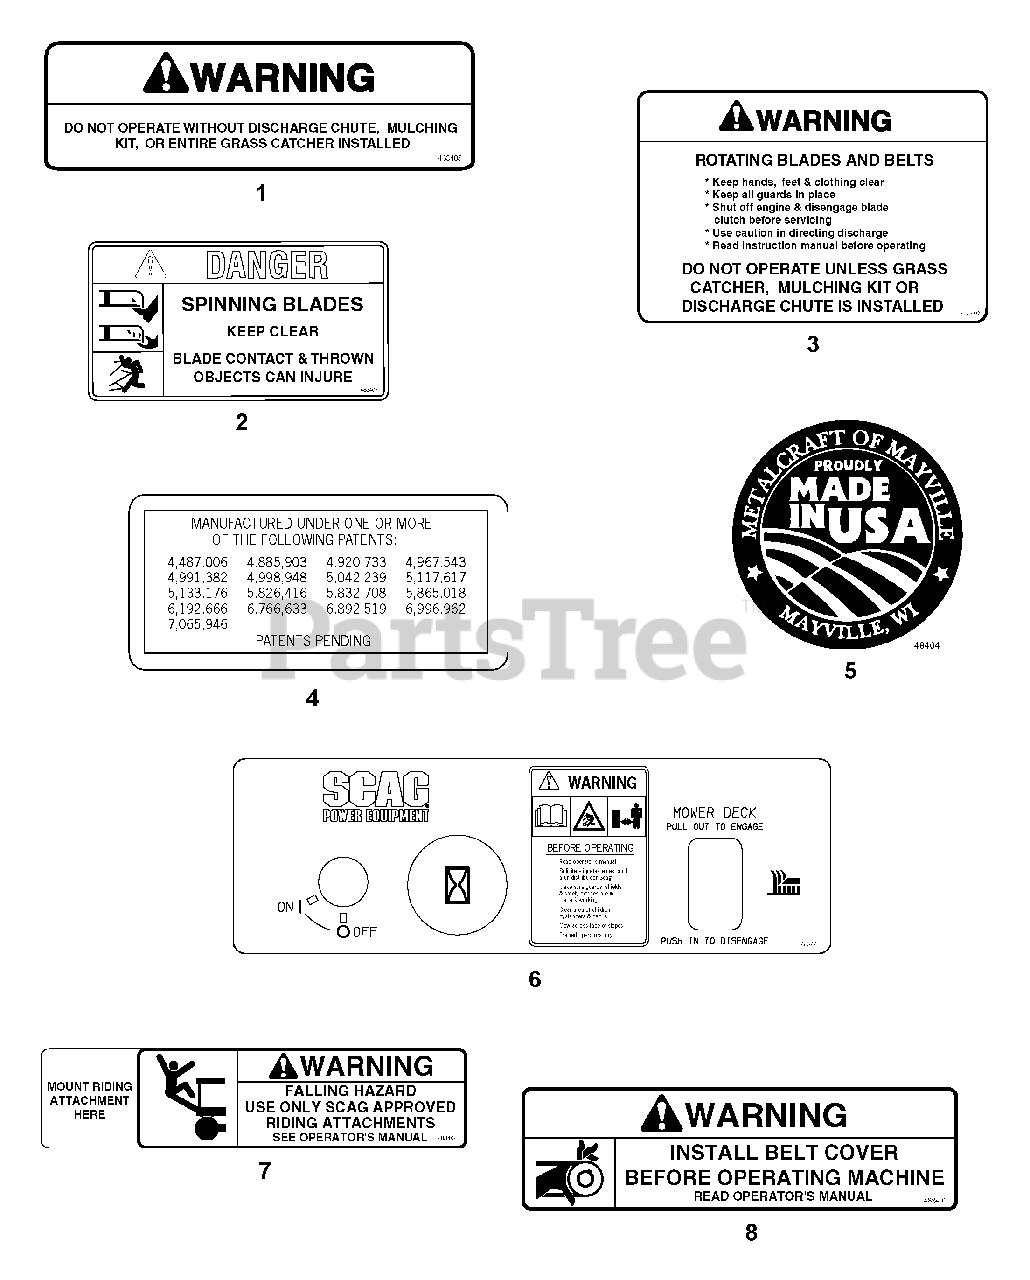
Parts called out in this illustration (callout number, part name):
1	Decal, Discharge Chute
2	Decal, Danger-Spinning Blades
3	Decal, Warning-Rotating Blades
4	Decal, Patents
5	Decal, Metalcraft - Made in USA
6	Decal, Instrument Panel - Rear
7	Decal, Sulky Attachment
8	Decal, Belt Cover
